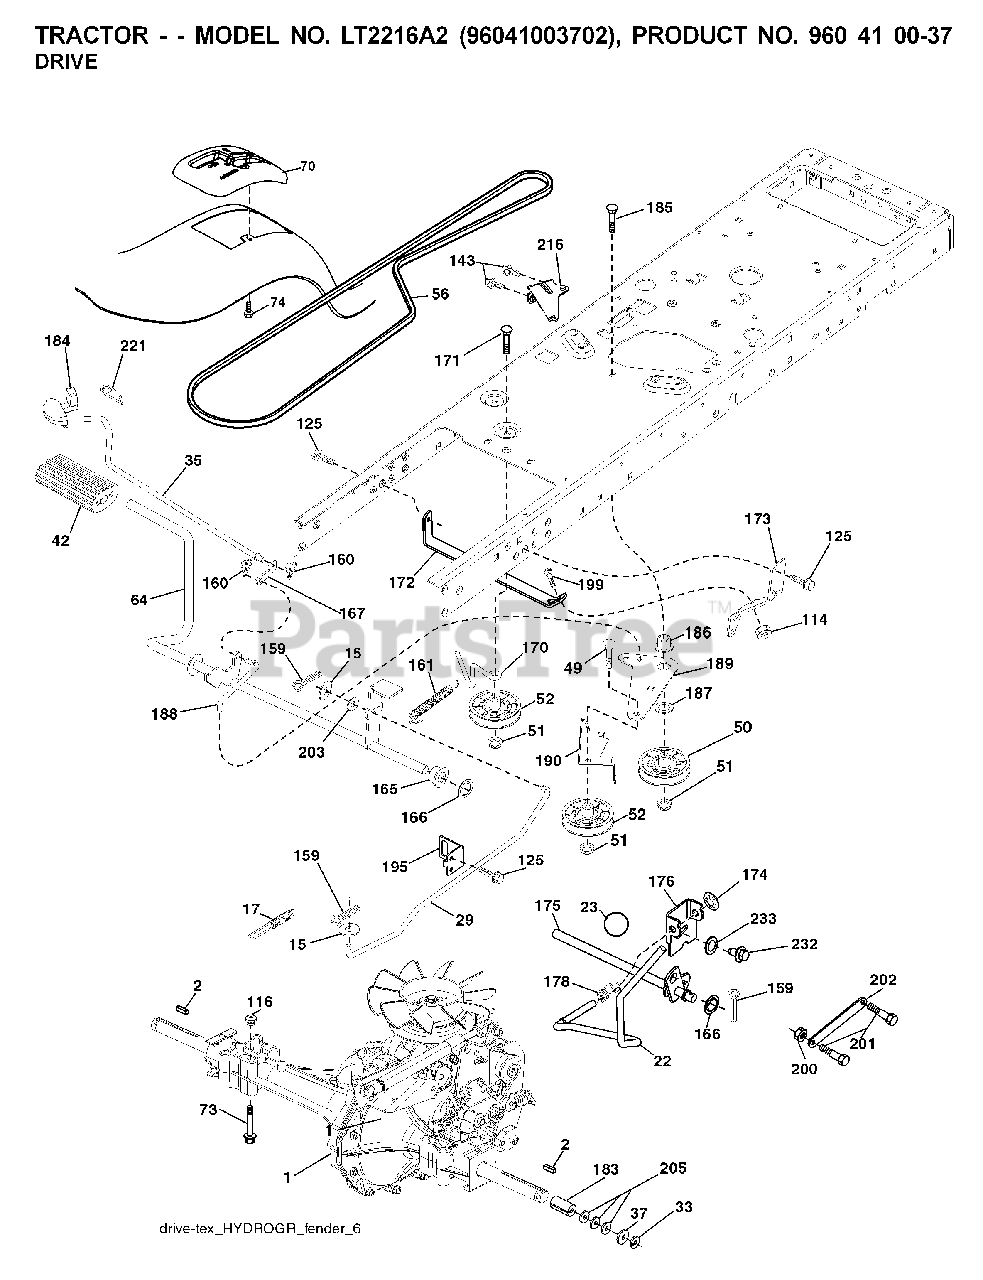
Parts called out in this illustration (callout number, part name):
2	SQUARE KEY
17	SPRING.BRAKE.HG3000/3500
22	ROD.SHIFT.FENDER.TLT.2006
23	PISTOL KNOB
29	ROD.BRAKE.HG-0510
33	E-RING LT
35	ROD.BRAKE.PARKING.LT.T
42	PEDAL COVER T
49	BOLT
50	IDLER.FLAT.910.OFFSET
51	NUT LOCK FLG 3/8-16 UNC
52	IDLER.V-GROOVE.910.OFFSET
64	SHAFT.ASM.PEDAL.BRAKE.
70	CONSOLE.SHIFT.STL.HYD.BLACK
73	BOLT HEX 5/16-18 GR 5
74	SCREW.HI-LO.CONSOLE
114	NUT.71038.31-18.HEX.NYLOCK
116	NUT LOCK HEX FLANGE 5/16-18
125	SCREW
159	COTTER PIN
160	RETAINER CLIP
161	SPRING, RETURN LT
165	BUSHING.SHAFT.BRAKE.HAND
166	NUT.PUSH.625.2006
167	LATCH.BRAKE.SPRING
170	KEEPER.V-IDLER.CENTER.
171	BOLT
172	STRAP.TRQ.LH.FS.HG0510
173	STRAP TORQUE RH
174	NUT.PUSH.500.2006
175	SHAFT.ASM.SHFT.HG0510/
176	ARM.CLEVIS.ROD.SHIFT
178	SPRING.SHIFT.GT2006
183	SPACER AXLE
184	HANDLE.PAKRING.BRAKE.
186	SPACER.RETAINER
187	WASHER 12/32X2X10GA
188	LINK.CLUTCH.GROUND.DRIVE
189	BELLCRANK.GROUND.DRIVE.TEX.
190	KEEPER.BELLCRANK.DRIVE
195	BRKT.ROD.BRAKE.18/20/2
199	BOLT
200	NUT.CENTERLOCK.5/16-
201	BOLT SHOULDER 5/16-18 UNC
203	WASHER
216	BRACKET.PULLEY.IDLER.W/TEX
221	RETAINER.SPRING.CLIP.H
232	BOLT FIN HEX 7/16-14 X 1
233	WASHER SERRATED
